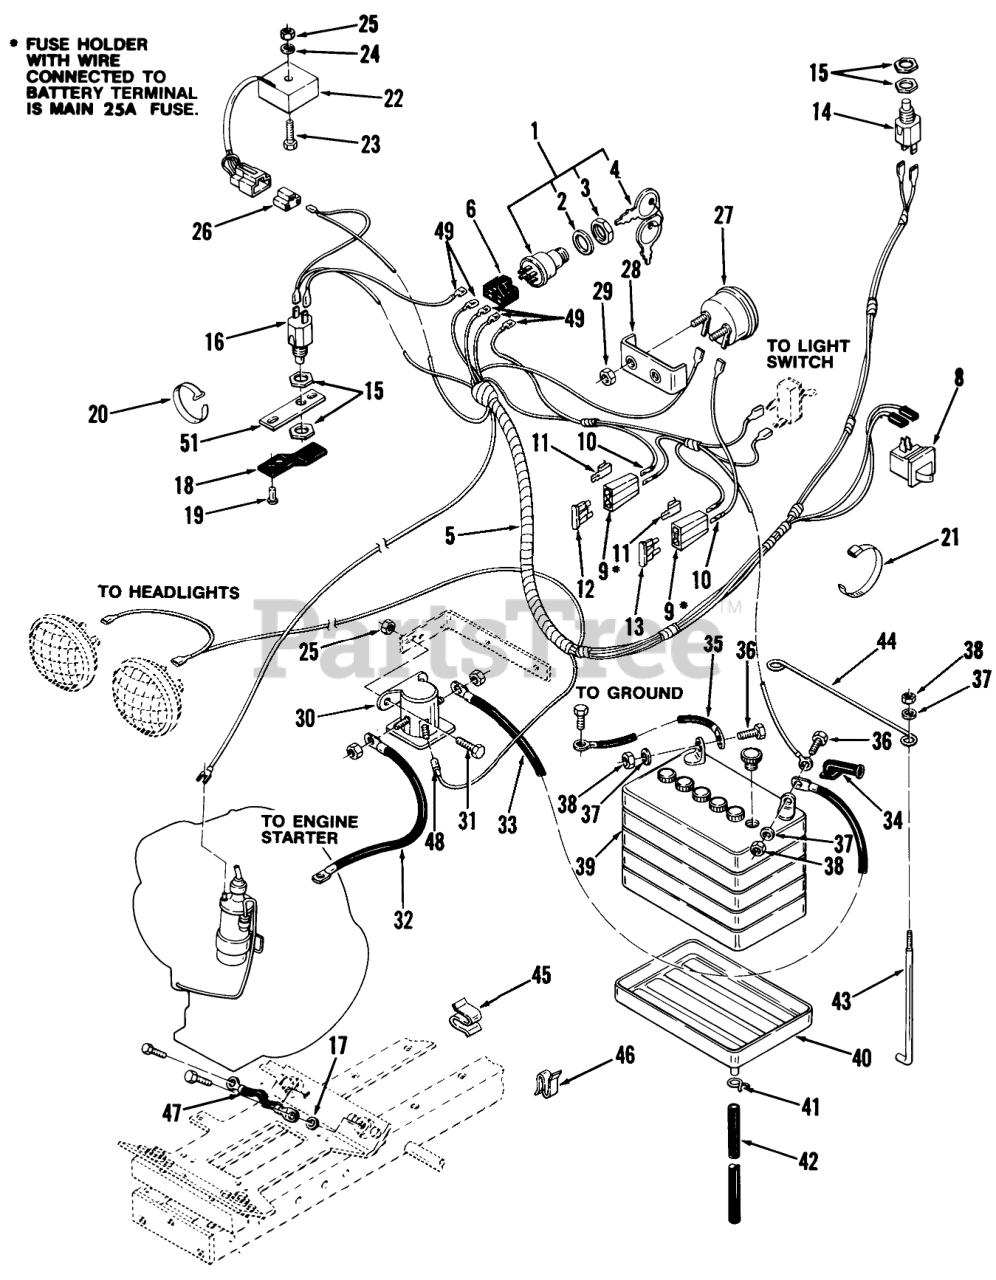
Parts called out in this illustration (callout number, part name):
1	SWITCH-IGNITION
2	LOCKWASHER
4	Key-EL
5	WIRING HARNESS
6	CONNECTOR-5 WAY-SERV
8	SWITCH INTERLOCK
9	AUTO-FUSEBLOCK TERM
10	TERMINAL-FUSE
12	FUSE-BLADE, 15 AMP
13	FUSE-BLADE, 25 AMP
14	SWITCH
15	NUT-HEX
16	SWITCH
17	LOCKWASHER
18	CLIP-SWITCH
19	RIVET
20	Cable Tie
21	PLASTIC TIE
22	RECTIFIER
23	Bolt
24	Washer
25	Nut
26	3-CONTACT CONNECTOR
27	AMMETER W/CLAMP
28	Clamp
29	HEX NUT 10-32 E.S.
30	SOLENOID
31	Screw
32	WIRE-GROUND
33	Cable
34	Boot
35	Wire
36	Bolt
38	Nut
39	Battery
40	TRAY-BATTERY
41	Clamp
42	TUBE-BATTERY DRAIN
43	Hook
44	ROD-HOLD DOWN
45	SPEED CLIP
46	CLIP
47	WIRE-GROUND
48	Terminal Part of 5
49	Terminal
51	CLAMP-PTO SWITCH
